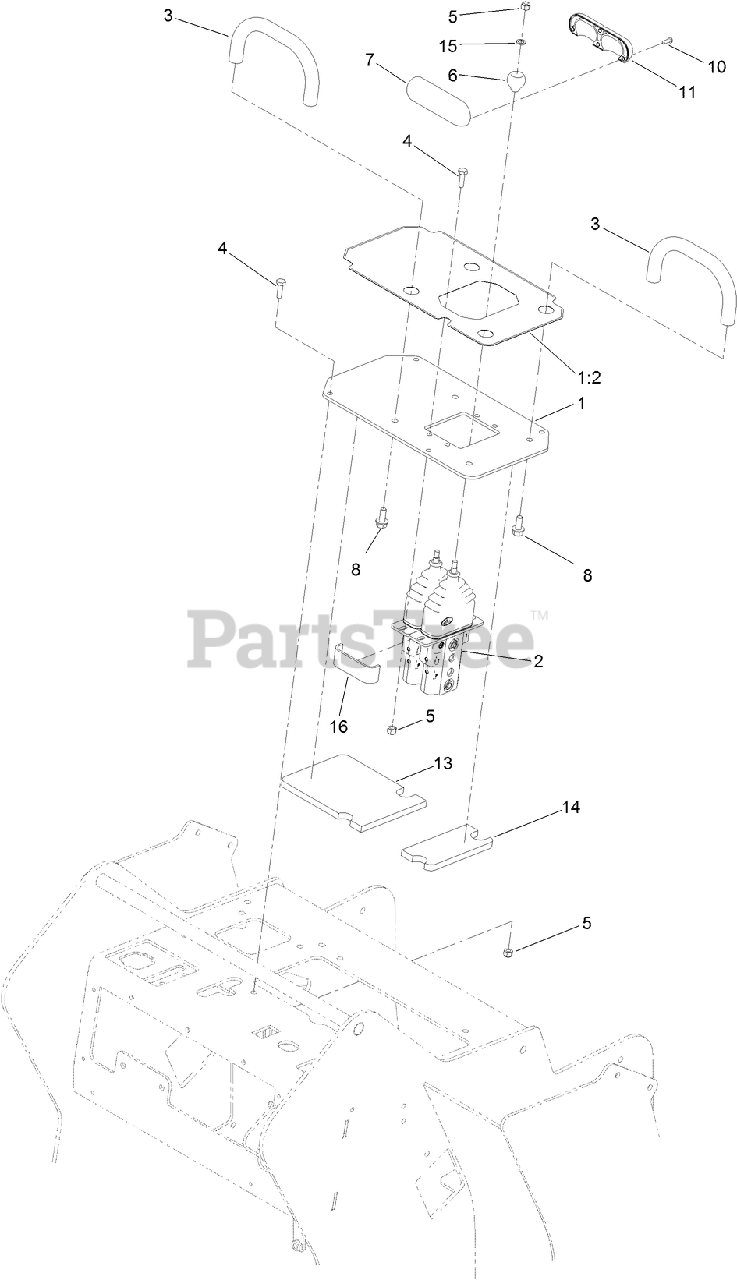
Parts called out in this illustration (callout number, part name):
1	PLATE-CONTROL
1:2	DECAL-CONTROL PANEL
2	VALVE-CONTROL
3	BAR-REFERENCE
4	SCREW-HH
5	NUT-LOCK, NI
6	BALL-TRACTION
7	HANDLE-CONTROL
8	SCREW-HHF
10	SCREW
11	HANDLE-TRACTION
13	FOAM-SHIELD, HEAT
14	FOAM-SHIELD, HEAT
15	SPACER-BEARING
16	TAPE-WIRE
